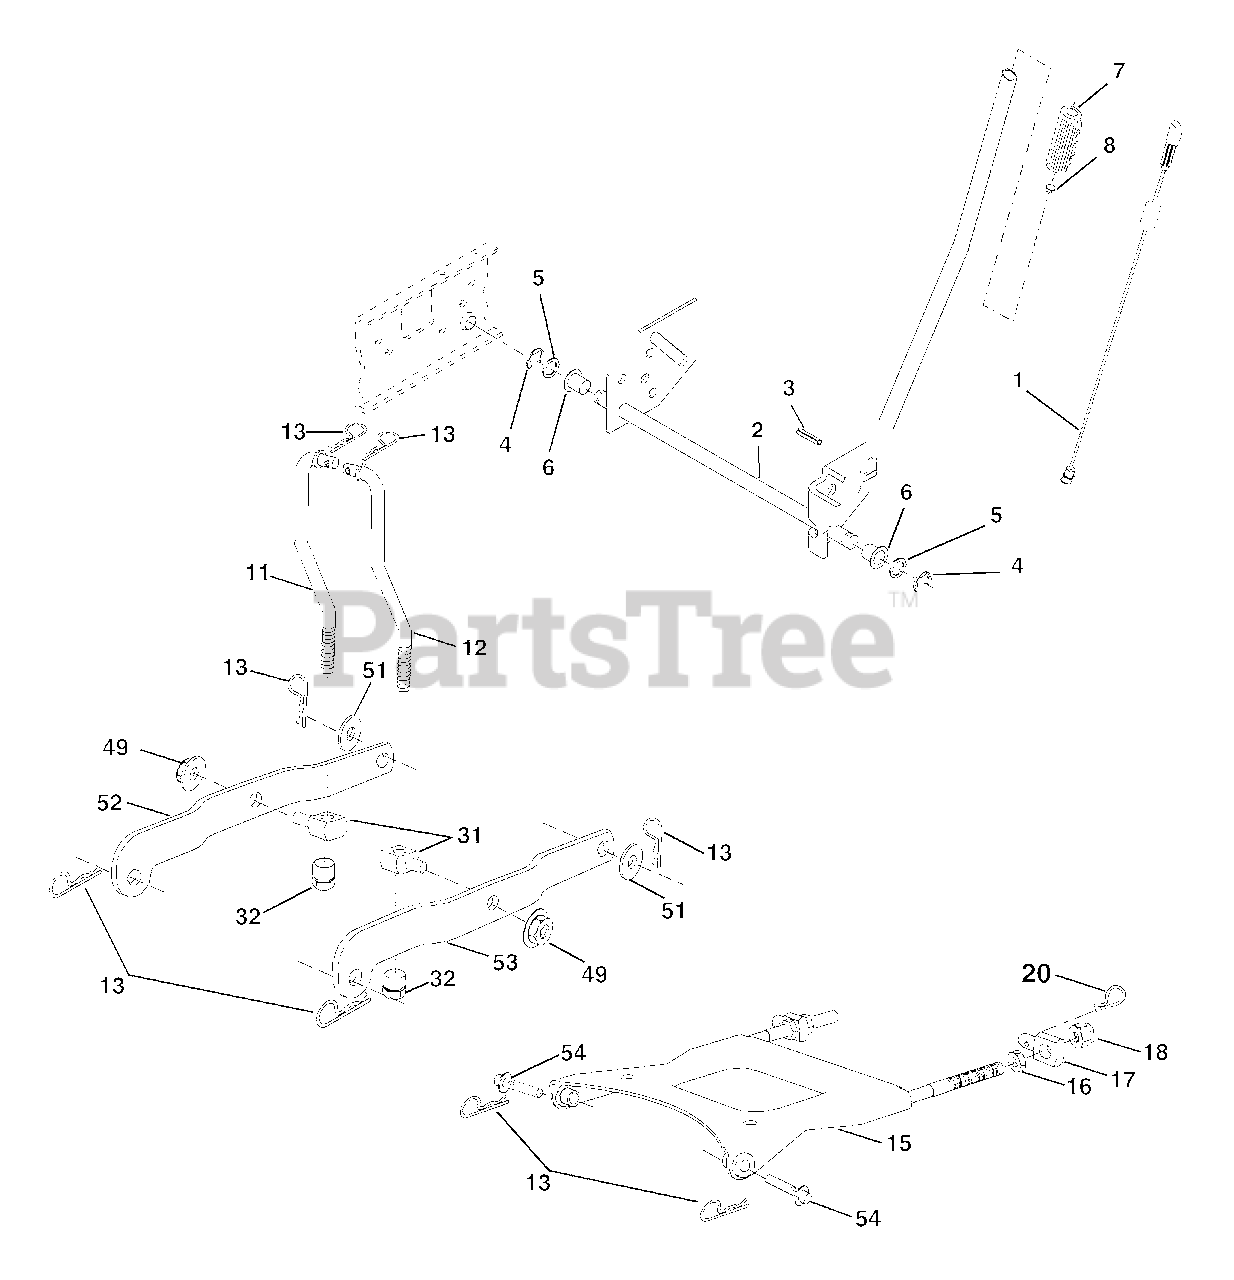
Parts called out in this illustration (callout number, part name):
1	Wire Asm Inner W/plunger 17 32
2	Shaft Asm Lift LH Inf Hgt P/L
3	Pin Groove 1 500 Zinc
4	E Ring #5133-62
5	Washer 21/32 x 1 x 21 Ga.
6	Bearing Nylon Blk 629 Id
7	Grip Handle
8	Button Plunger
11	Link Lift LH
12	Link Lift RH
13	Retainer Spring
15	Plate Asm Suspension Front
16	Nut Jam Hex 1/2-13 unc
17	Trunnion Blk Zinc
18	Nut Lock W/wsh 1/2-13 unc
20	Retainer Spring
31	Trunnion Suspension Arm
32	Nut Lift Link 7/16-20
49	Nut Hex Flange Lock
51	Washer 17/32 x 7/8 x 16 Ga.
52	Arm Suspension Rear LH
53	Arm Suspension Rear RH
54	Pin Flange
